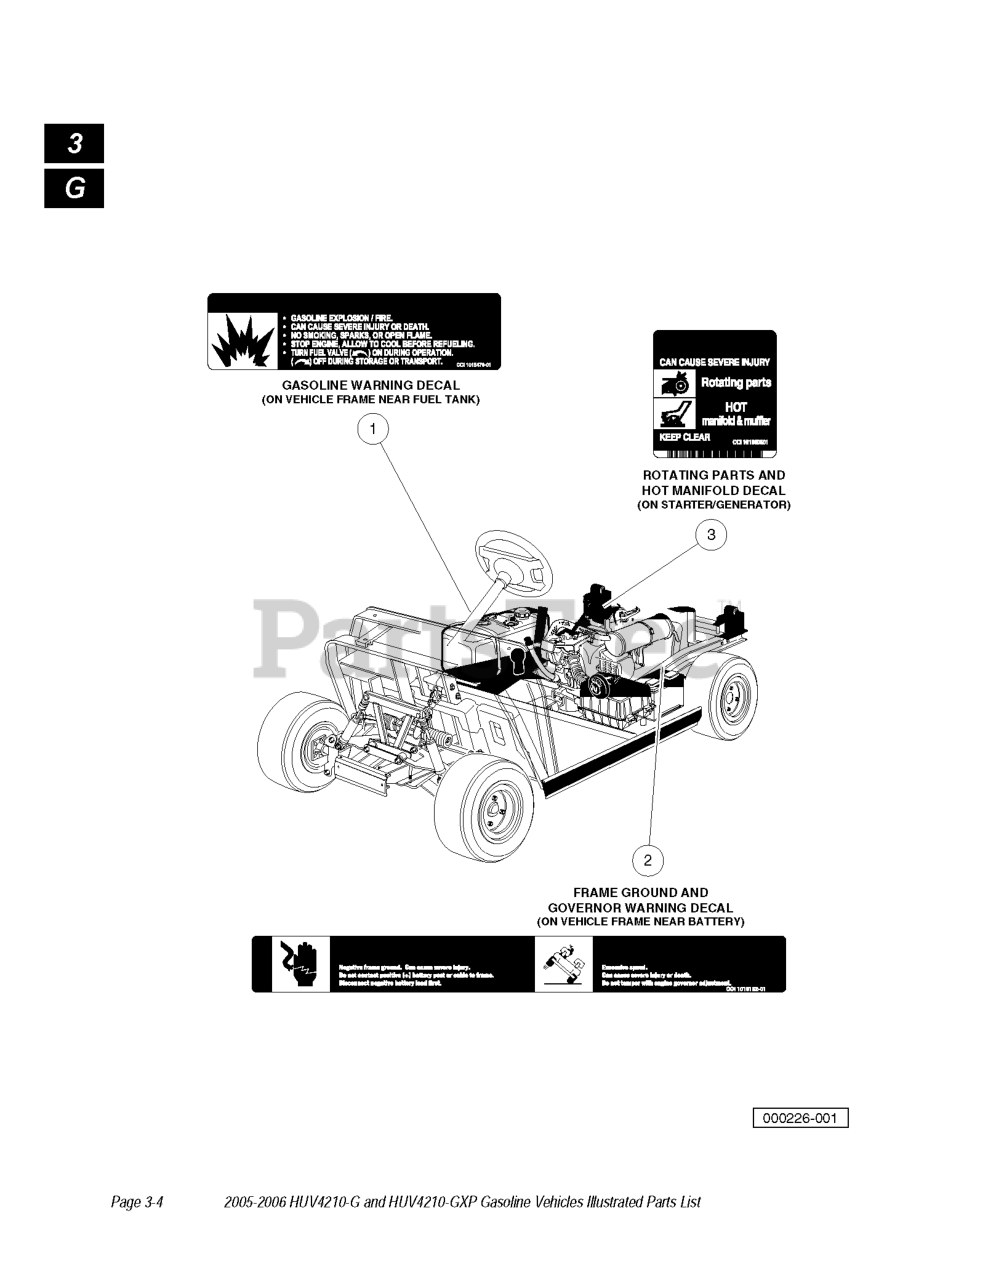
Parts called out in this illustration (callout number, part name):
1	DECAL, WARNING - GASOLINE FUEL
2	DECAL, FRAME GROUND, GOV. WARN
3	DECAL, ROTATING PARTS/MANIFOLD
